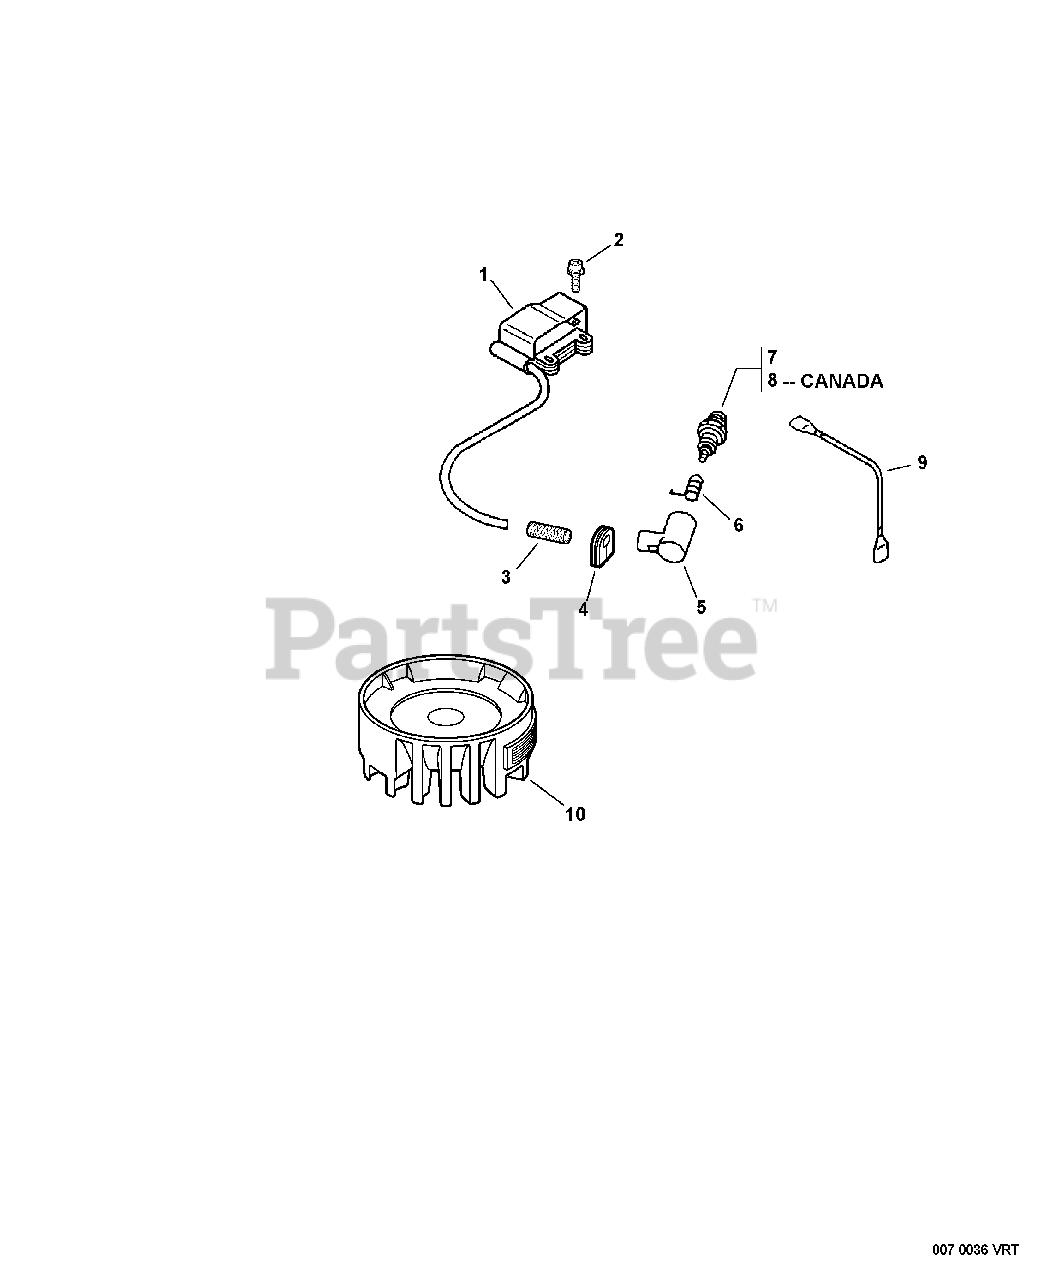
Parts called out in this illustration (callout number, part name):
1	COIL, IGNITION
2	BOLT 4×20
3	TUBE, INSULATOR
5	CAP, SPARK PLUG
6	TERMINAL, SPARK PLUG
7	SPARK PLUG - BPM8Y
8	SPARK PLUG - BPMR8Y
9	LEAD - IGNITION
10	FLYWHEEL
